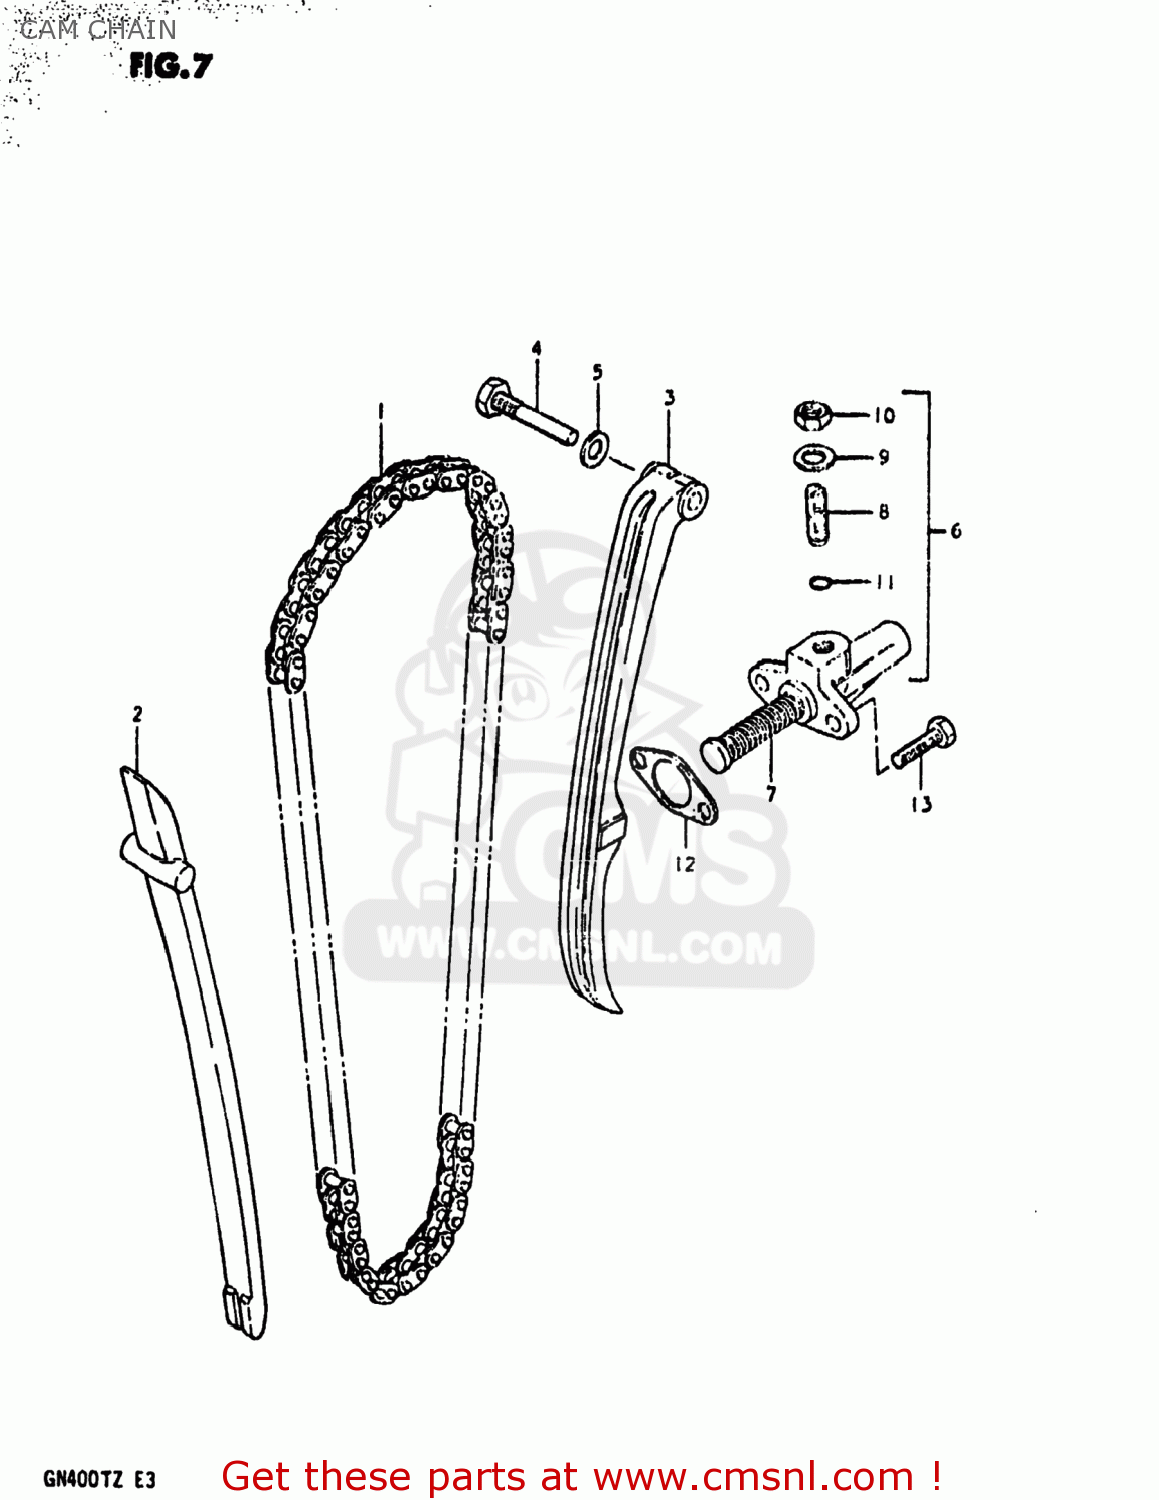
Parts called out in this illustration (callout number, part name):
1	CHAIN,CAMSHAFT DRIVE
2	GUIDE,CAM CHAIN
3	TENSIONER,CAM CHAIN
4	BOLT,CAM CHAIN TENSIONER
5	GASKET 8.2X14X1 (NAS)
6	ADJUSTER,CAM CHAIN TENSIONER
7	SPRING
8	SCREW
9	WASHER
10	NUT
11	O-RING
12	GASKET,TENSIONER ADJUSTER (NAS)
13	BOLT,M6X1X20
